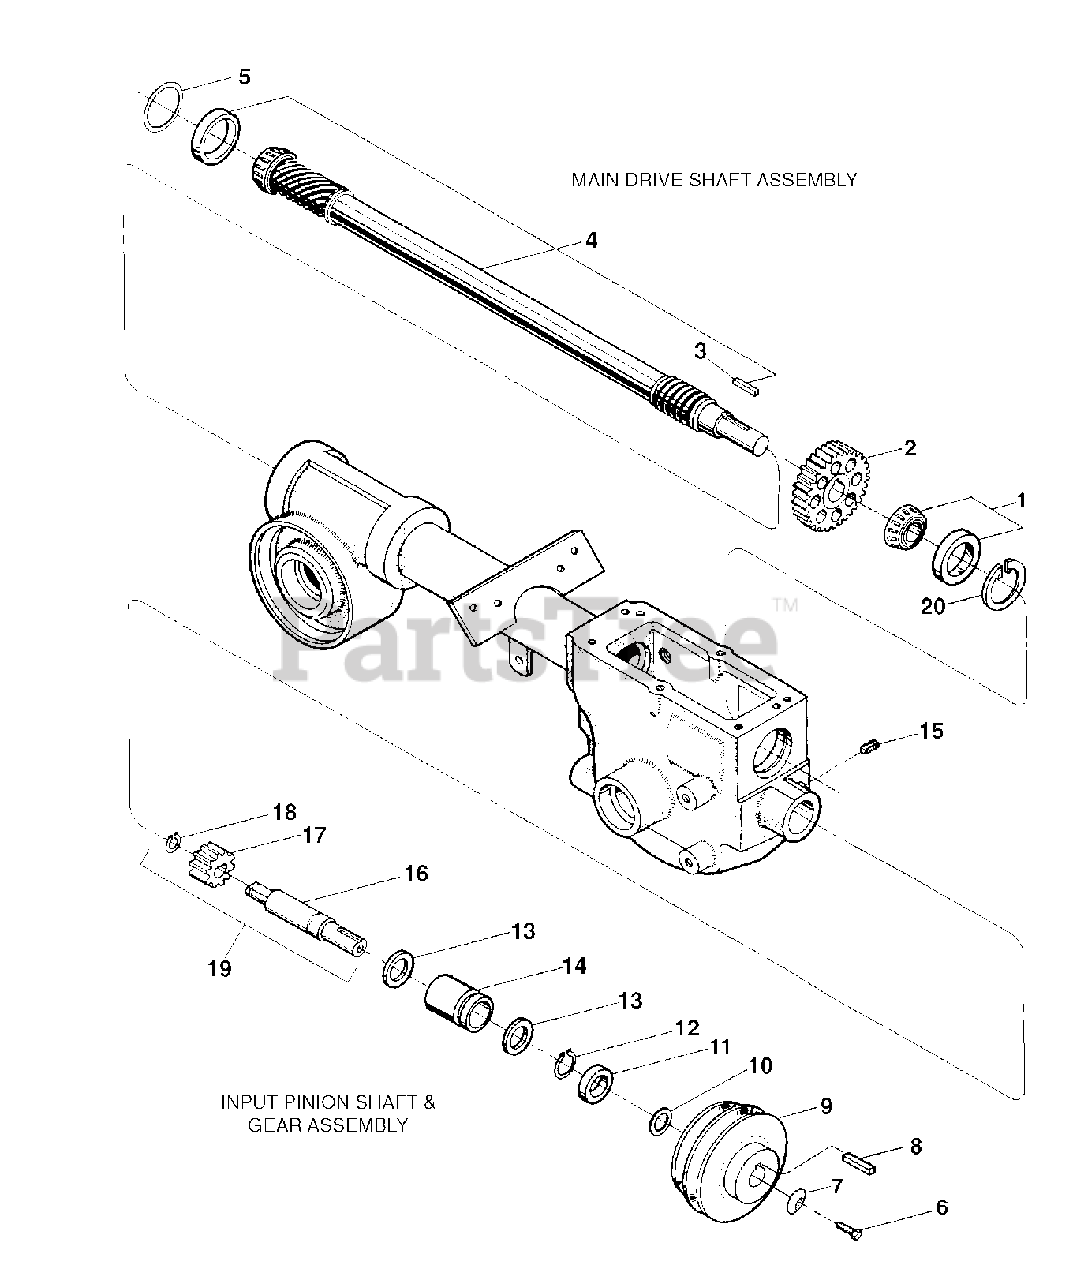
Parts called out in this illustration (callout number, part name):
1	Bearing, Tapered Roller with Race
2	Spur Gear
3	Key, 3/16 sq. x 1
4	Main Drive Shaft
5	Shim, Rear Bearing Cap, .010" thick
5	Shim, same as above, but .030" thick
5	Shim, same as above, but .005" thick
6	Hex Hd. Screw, 5/16-24 x 1-1/8
7	Washer, Disc Spring (concave surface faces pulley)
8	Key, 3/16 sq. x 1-1/2
9	Transmission Drive Pulley
10	Support Washer
11	Oil Seal, Input Pinion Shaft
12	Retaining Ring (external)
13	Thrust Washer
14	Bushing
15	Set Screw, 5/16-18 x 3/8
16	Input Pinion (steel shaft)
17	Input Pinion Gear
18	Retaining Ring (external)
19	Pinion Assy.
20	Retaining Ring (internal)
